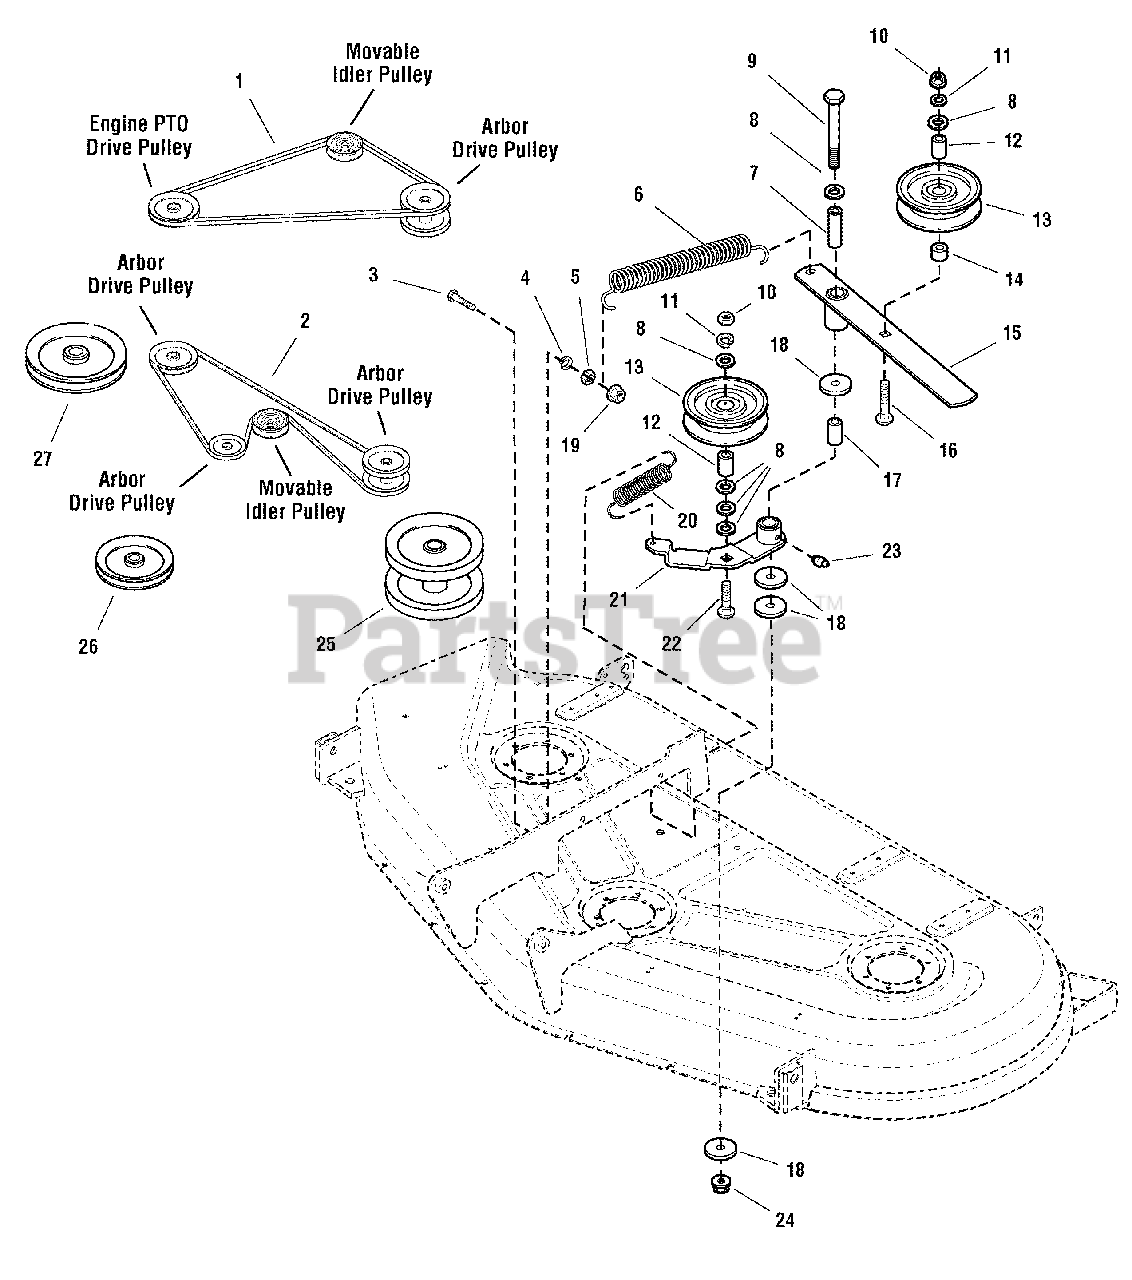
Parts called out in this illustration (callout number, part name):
1	V-BELT, Engine PTO
2	V-BELT, 54 Mower Deck
3	CAPSCREW, Hex Head, 5/16-18 x 1-1/4
4	WASHER, Lock, 5/16
5	NUT, Hex, 5/16-18
6	SPRING
7	SPACER, 25/64 x 5/8 x 1-55/64
8	WASHER, 3/8
9	CAPSCREW, Hex Head, 3/8-16 x 4-1/2
10	NUT, Hex, 3/8-16
11	WASHER, Lock, 3/8
12	HUB, 25/64 x 3/4 x 63/64, Powder Metal
13	PULLEY, Idler (Includes Ref. No. 12)
14	SPACER
15	ASSEMBLY, Lever
16	CARRIAGE BOLT, 3/8-16 x 2
17	SPACER
18	WASHER, 3/8
19	NUT, Hex Centerlock, 5/16-18, Black
20	SPRING, Extension, 4" Long
21	LEVER ASSEMBLY, (Includes Ref. No. 23)
22	CARRIAGE BOLT, 3/8-16 x 1-1/2
23	FITTING, Lube
24	NUT, Hex Flange, 3/8-16
25	PULLEYS & HUB ASSEMBLY, Double, LH
26	PULLEY & HUB ASSEMBLY, Center
27	PULLEY & HUB ASSEMBLY, RH
